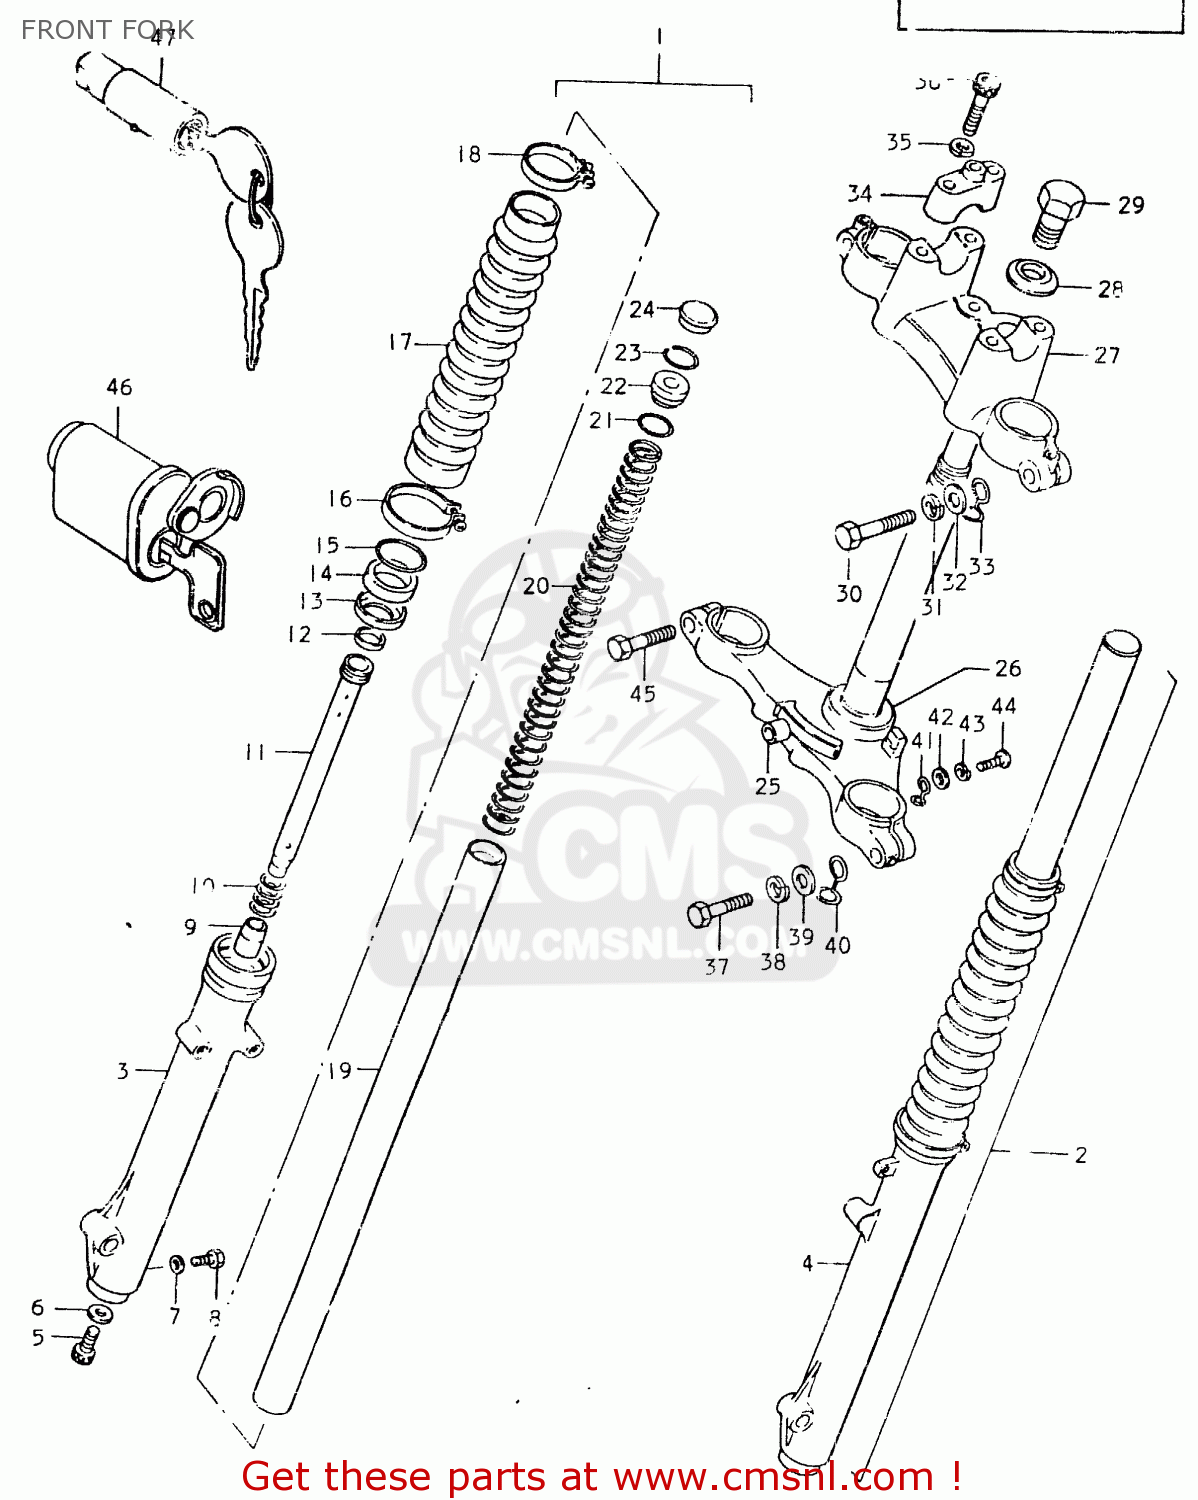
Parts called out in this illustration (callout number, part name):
1	DAMPER ASSY, RH
2	DAMPER ASSY, LH
3	TUBE,FORK,OUTER,RIGHT
4	TUBE,FORK,LEFT,OUTER
5	BOLT(8X27)
6	GASKET (NAS)
7	GASKET,DRAIN,PLUG (NAS)
8	BOLT(6X8)
9	PIECE,OIL LOCK
10	SPRING,REBOUND
11	CYLINDER
12	RING,PISTON
13	WASHER,FRONT FORK OIL SEAL
14	OIL SEAL,FRONT FORK
15	CIRCLIP,FORK OIL SEAL
16	CLAMP
17	BOOT
18	BAND
19	TUBE,FORK,INNER
20	SPRING
21	O RING
22	SEAT,SPRING
23	RING,STOPPER
24	CAP,FRONT FORK
25	STEM,STEERING
26	RACE,STEERING OUTER LWR
27	HEAD,STEERING STEM
28	WASHER(10.5X30X2.3)
29	BOLT
30	BOLT
31	LOCK WASHER
32	WASHER
33	CLIP
34	HOLDER,HANDLEBAR
35	LOCK WASHER
36	BOLT 8X35
37	BOLT 12X45
38	WASHER,LOCK 12
39	WASHER
40	CLIP
41	CLIP
42	WASHER
43	LOCK WASHER
44	SCREW 6X12
45	BOLT
46	LOCK ASSY, STEERING (NEIMAN TYPE EXECUTE
47	LOCK ASSEMBLY,STEERING (NEI
